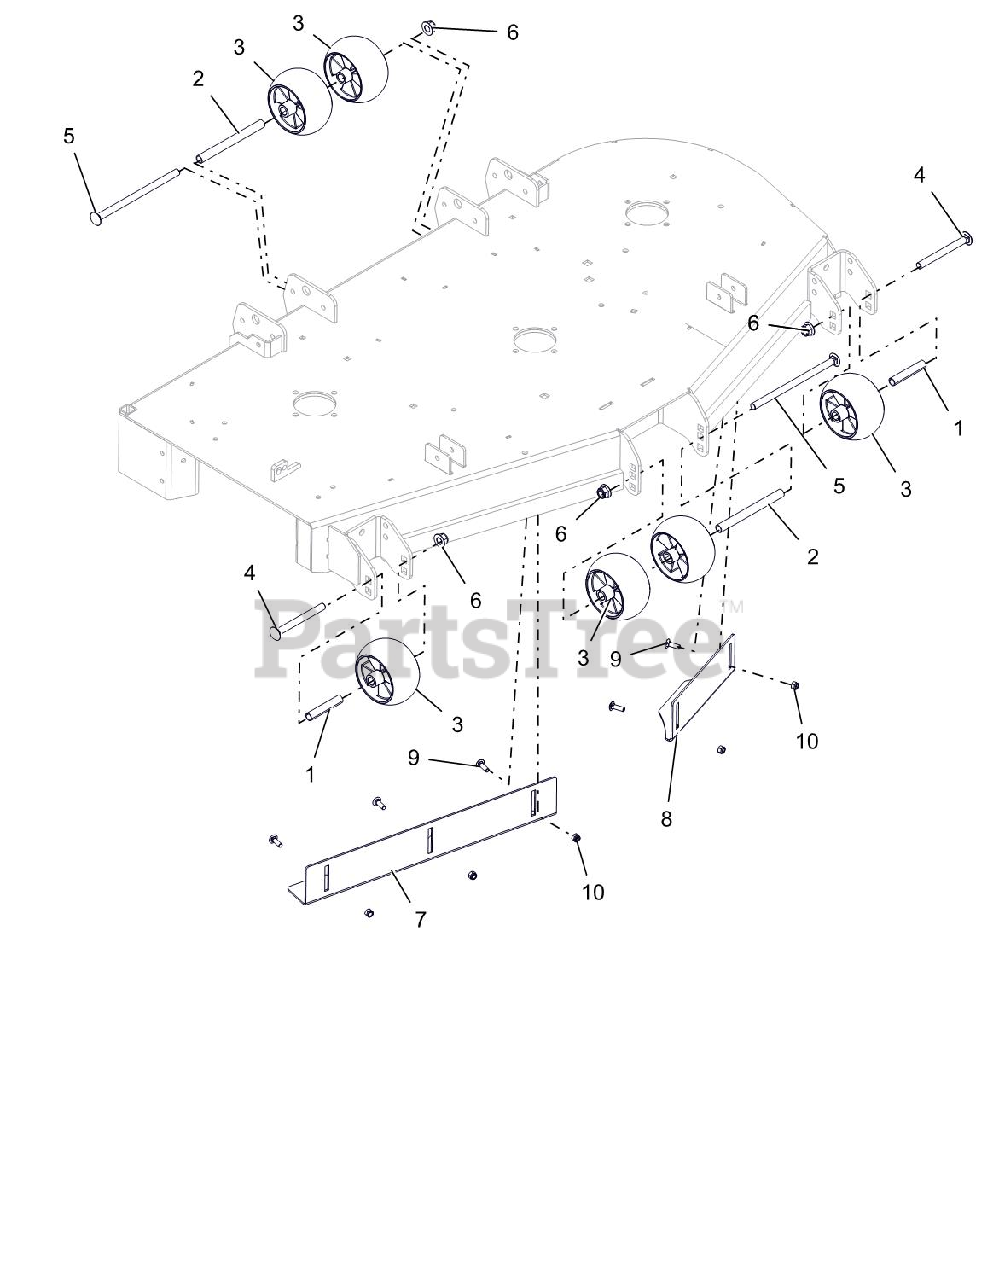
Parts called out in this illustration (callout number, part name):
1	SPACER, .510X.625X3.35
2	SPACER, .510X.625X6.50
3	ANTI-SCALP WHEEL - 5X3 CTR
4	BLT-RDHDSQNK .50-13X5.00 GR5YZ
5	@BLT-RDHDSQNK .50-13X8.50 G5YZ
6	@NUT-LK-NYL-FLG .50-13 YWZC
7	52" RH VACUUM BAFFLE - BLK
8	52" LH VACUUM BAFFLE - BLK
9	@BLT-RDHDSQNK .31-18X1.00 G5YZ
10	@NUT-LK-NYL .312-18 YWZC
